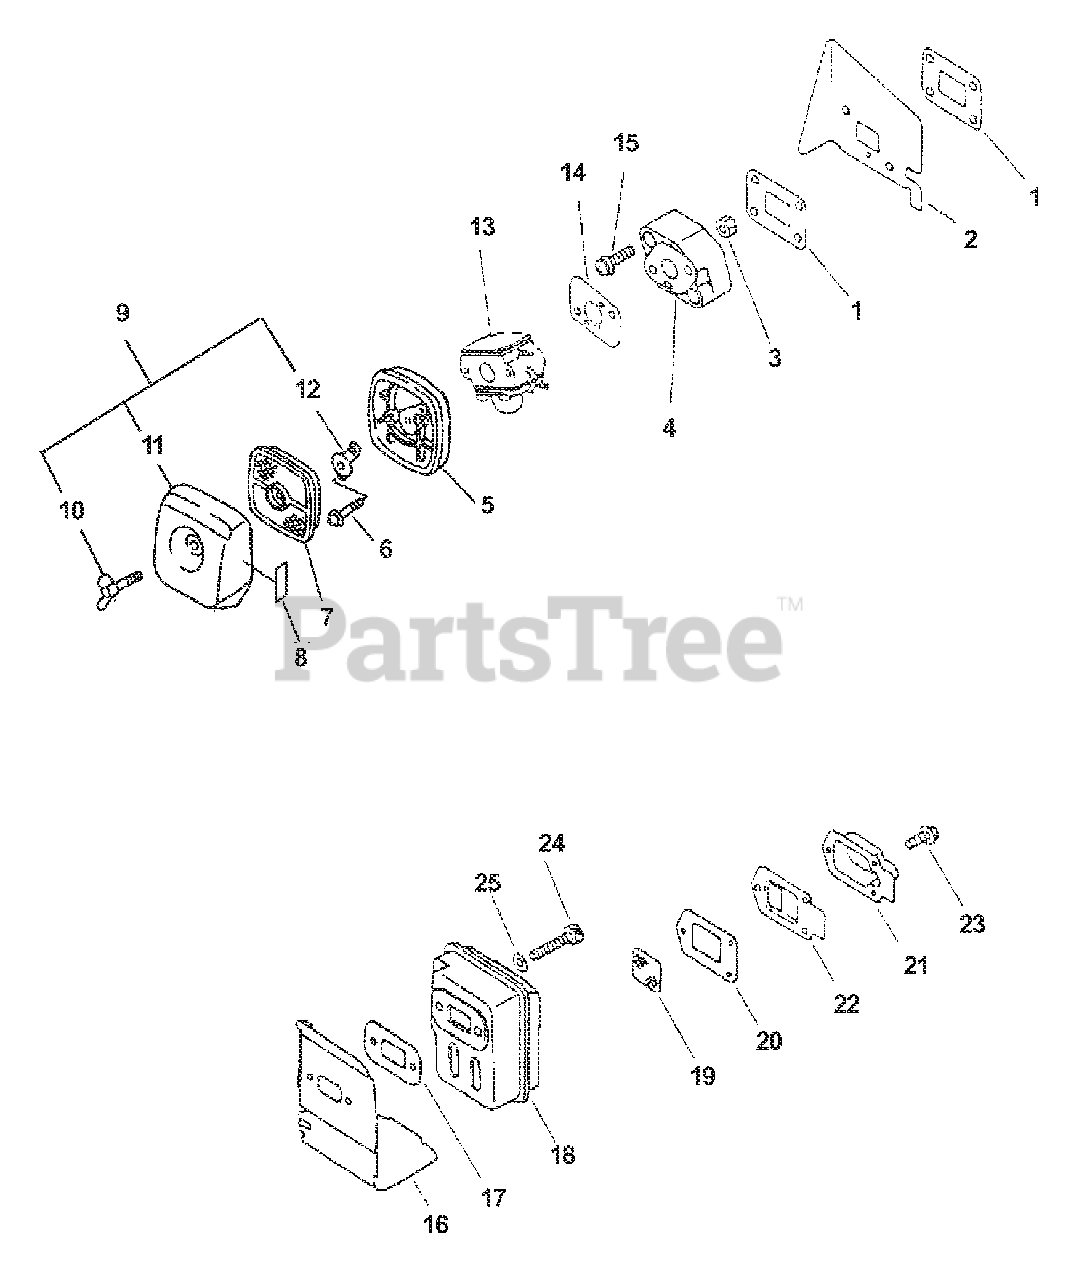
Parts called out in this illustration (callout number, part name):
1	GASKET, INTAKE
2	SHIELD, INTAKE
4	INSULATOR, INTAKE
5	AIR FILTER CASE ASSY
6	SCREW - 5X65
7	FILTER, AIR - SINGLE LAYER
8	LABEL - CHOKE
9	COVER, AIR FILTER - GRAY
10	THUMBSCREW
11	COVER, AIR FILTER - GRAY
12	PLATE, PREVENT
13	CARBURETOR C1U-K43
14	GASKET, INTAKE
15	SCREW - 5X22
16	SHIELD, EXHAUST
17	GASKET, EXHAUST
19	SCREEN, SPARK ARRESTOR
20	GASKET, EXHAUST
21	GUIDE, EXHAUST
21	GUIDE, EXHAUST - OUTER
22	GASKET, EXHAUST - INNER
23	SCREW - 4X10
24	SCREW - 5X55
25	WASHER - 5
